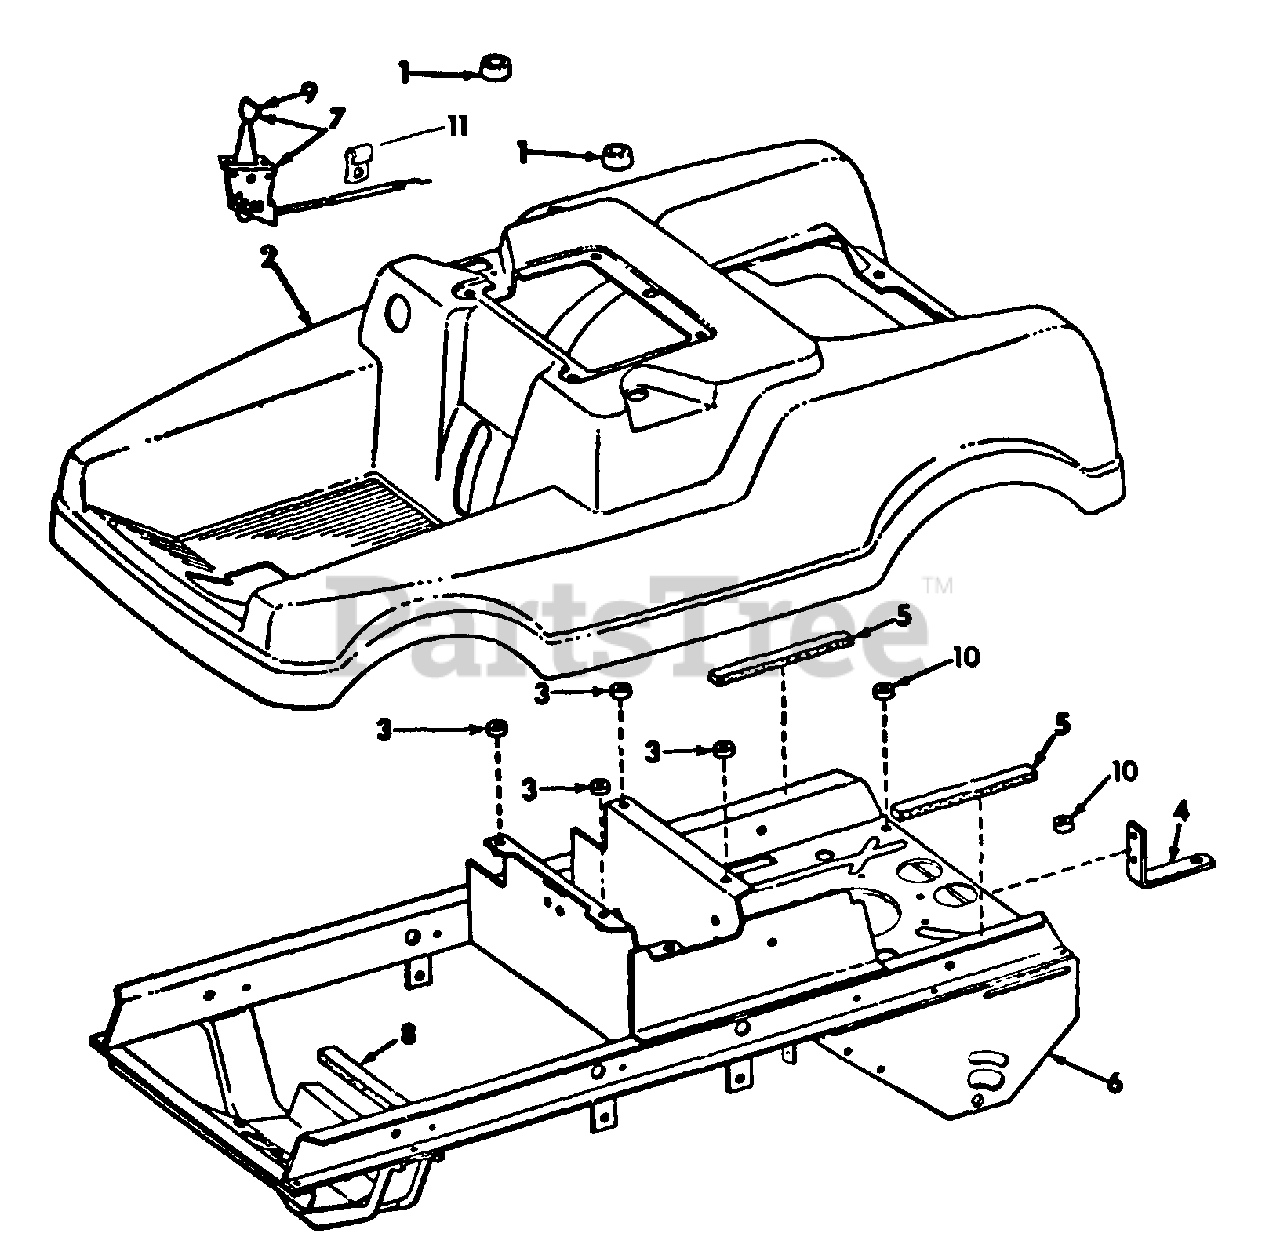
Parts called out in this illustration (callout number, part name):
1	BUMPER, SEAT SUPPORT REAR
2	BODY W/PLUG, 432 485 AND PLUG, 432 580, RIDING MOWER
3	SPACER, BODY MOUNTING
4	ANGLE, DRAWBAR
5	STRIP, FOAM GASKET SEALING
6	FRAME W/PRODUCT GRAPHIC, IH-120391-C1 ASSY, MAIN
7	CONTROL, THROTTLE
8	STRIP, FOAM GASKET SEALING
9	KNOB, THROTTLE CONTROL
10	SPACER BODY MTG REAR
